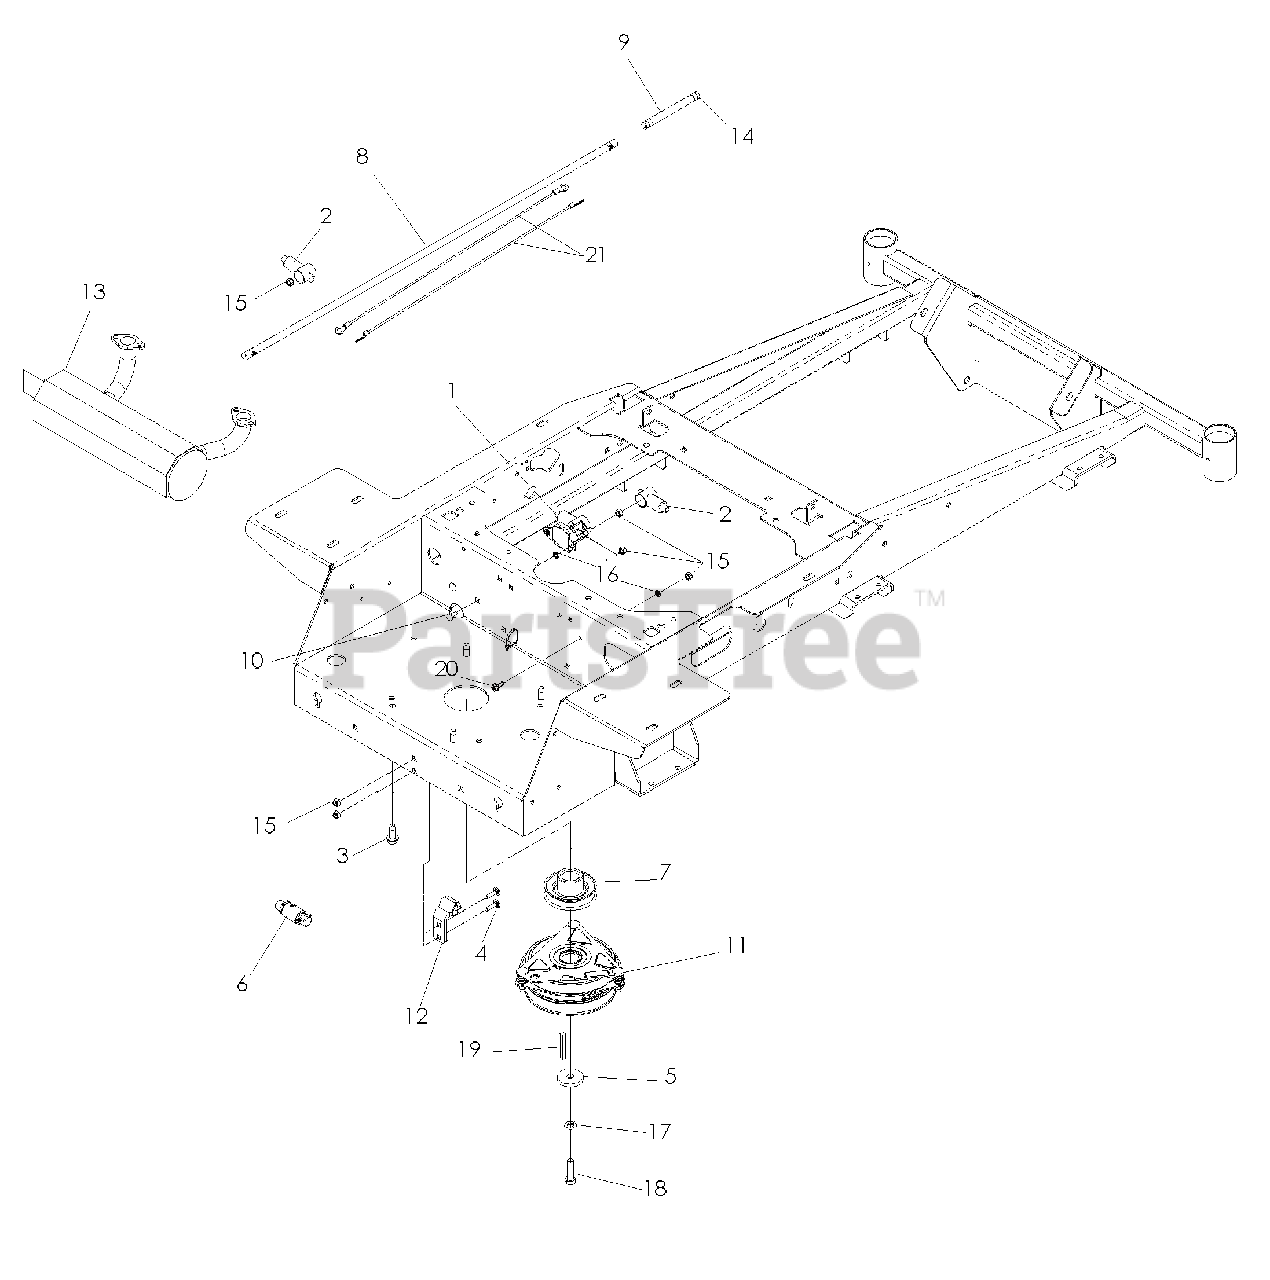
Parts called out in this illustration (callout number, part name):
1	SOLENOID
2	INSULATOR
3	BOLT 3/8-16 X 1.0
4	RHSNB, 1/4-20 X 1, GR5
5	SPINDLE WASHER
6	OIL DRAIN FITTING
7	PULLEY, DRIVE
8	HOSE 35"
9	FUEL LINE 5"
10	RHSSNB, 1/4-20X5/8
11	CLUTCH, 150 FT/LBS
12	TIE DOWN, CLUTCH
13	MUFFLER KOHLER COURAGE TWIN
14	HOSE CLAMP
15	NUT 1/4-20 NYLOC
16	WASHER 1/4 INT TOOTH
17	WASHER 7/16 LOCK
18	HCS 7/16F X 1 1/2
19	KEY 1/4 SQ X 2
20	SCREW- 1/4-20 X 5/8
21	CABLE POSITIVE, LONG
